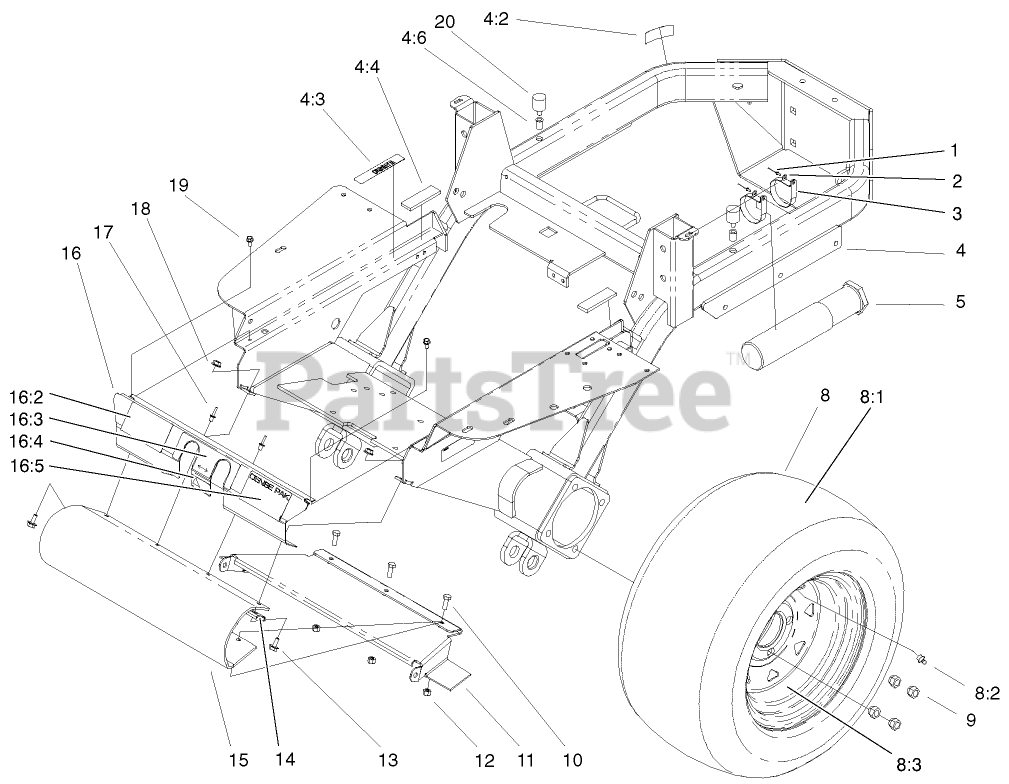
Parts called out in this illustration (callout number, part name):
1	RIVET-BLIND
2	WASHER-FLAT
3	CLAMP-R
4	FRAME ASM W/ DECALS
4:2	DECAL-HOT SURFACE
4:3	DECAL-WARNING
4:4	PAD-RUBBER
4:6	INSERT-THREADED
5	TUBE-MANUAL
8	Tire And Wheel ASM
8:1	Tire
8:2	STEM-VALVE
8:3	WHEEL
9	NUT-LUG
10	SCREW-HH
11	COVER-DRIVESHAFT
12	NUT-LOCK, NI
13	SCREW-HHF
14	BRACKET-GUARD
15	GUARD-FOOTREST
16	COVER PLATE ASM
16:2	DECAL - Z355
16:3	DECAL - OPERATION
16:4	DECAL-PROTECTION, EAR
16:5	DECAL-PAK, DENSE
17	RIVET-BLIND
18	NUT-HF
19	SCREW-HWH
20	BUMPER-RUBBER
